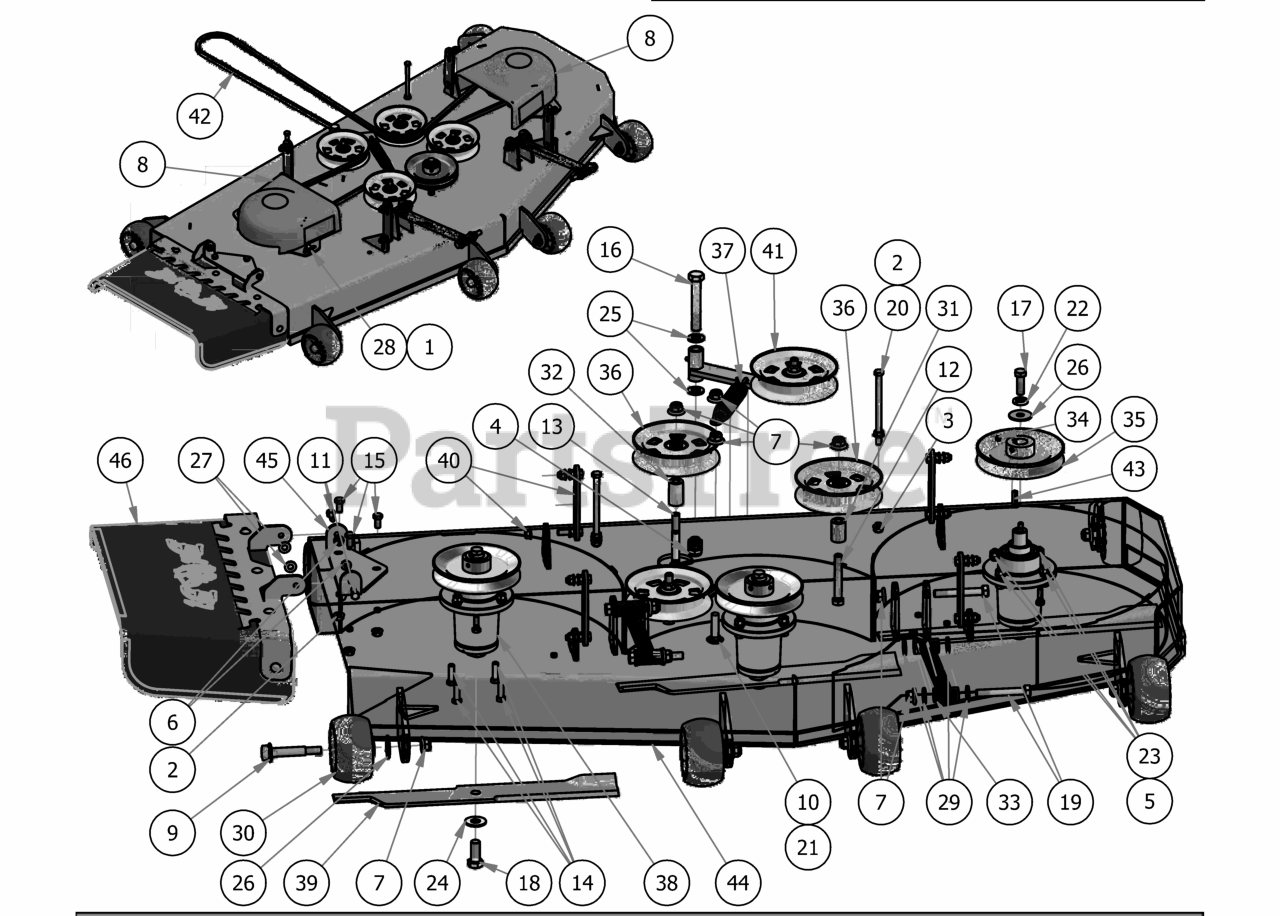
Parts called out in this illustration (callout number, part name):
1	Acorn nut-pulley Cover
2	3/8" Flange Nut
3	3/8" Nylock Flange Nut
4	5/8-11 Nylon Insert Jam Half Nut
5	3/8" Hex Nut
6	5/16" Nylon Flange Nut
7	1/2-13 Nylon Flange Nut
8	Pulley Cover
9	Deck Wheel Bolt
10	1/2 x 2" Carriage Bolt
11	5/16-18 x 1 GR 5 Hex Bolt Zinc
12	1/2 x 3 1/2 Flange Bolt Grade 8
13	1/2" x 4" Bolt (Grade 8)
14	3/8" x 1 1/4" Hex Bolt
15	3/8" x 3/4" Hex Bolt
16	5/8" x 4" Hex Bolt
17	1/2"-20 x 1 1/2 - Grade 5 Fine Thread Bolt
18	5/8 x 1 1/2 Grade 8 Hex Bolt (Fine)
19	1/2-13 x 3 1/2 GR 5 Hex Bolt
20	3/8-16 x 5 1/2 Hex Bolt
21	.517 Square Hole Round Washer
22	1/2" Lock Washer Zinc
23	3/8" Lock Washer
24	5/8'' Flat Washer
25	.630 ID Plastic Washer
26	1/2" Belleville Washer
27	.360 ID Plastic Washer
28	.360 ID Plastic Washer-Black
29	.505 Nylon Spacer
30	Deck Wheel
31	Idler Pulley Standoff
32	1 3/4" Pulley Spacer
33	MZ/ZT Deck Locator
34	5/16 Set Screw
35	6 1/4" Drive Pulley
36	5-3/4 Idler Pulley
37	Deck Idler Spring
38	Spindle Assembly
39	60 Inch Fusion Blade
40	Deck Hanger Assembly
41	2017 MZ/ZT Deck Idler Assembly
43	1/4" x 1" Key
44	60 ZT Welded Deck Shell
45	Discharge Chute Hanger (deck mounted)
46	Discharge Chute Assembly
